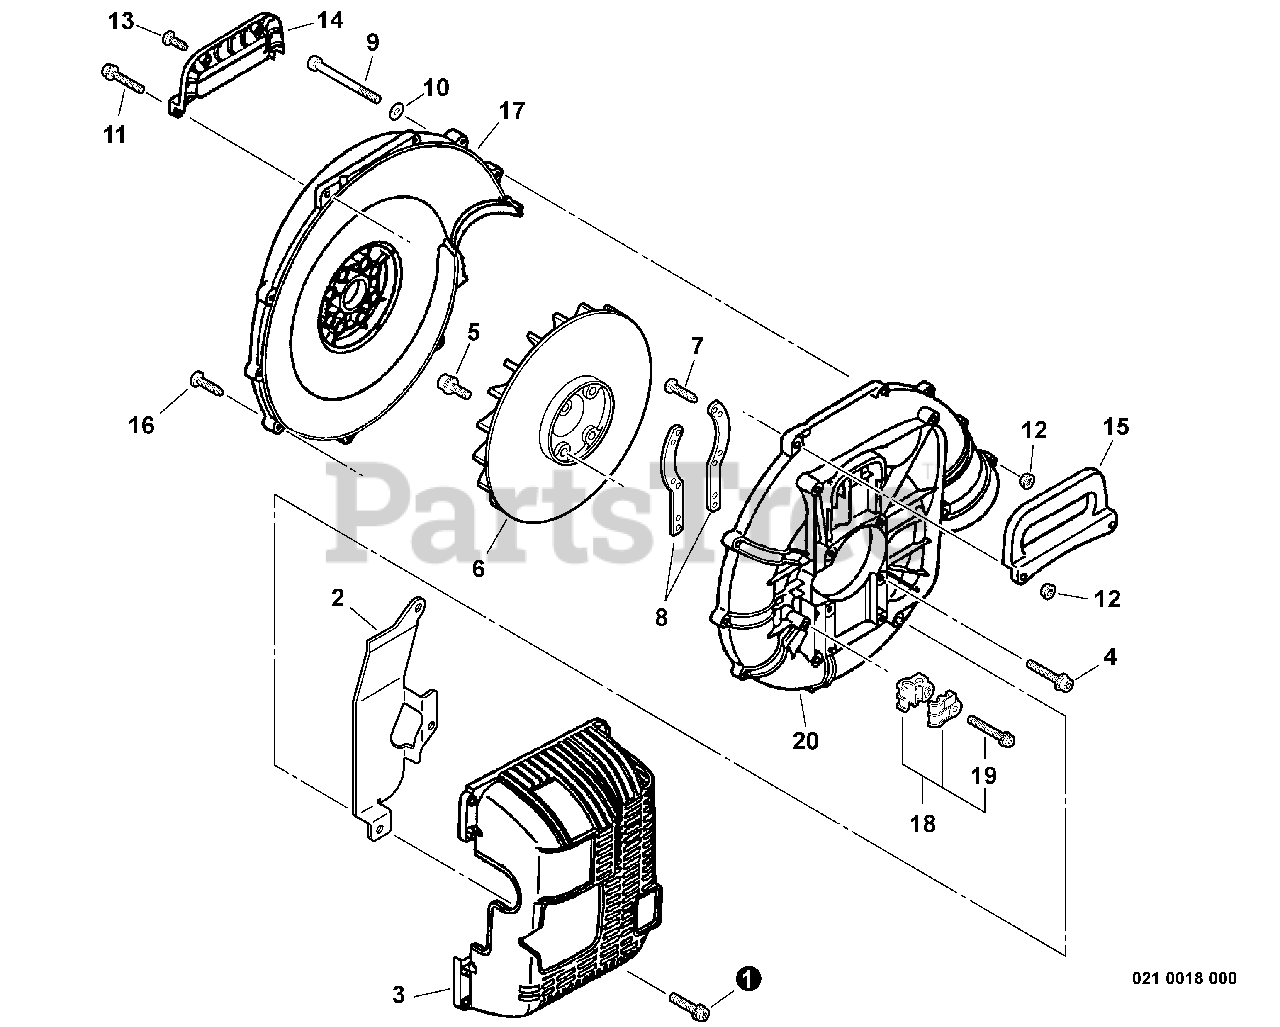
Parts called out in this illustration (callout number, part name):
1	SCREW - 5X18
2	INSULATOR
3	COVER, ENGINE
4	SCREW - 5X32
5	SCREW - 5X20
7	SCREW - 3X12 -- TAPPING
8	BRACKET, ENGINE
9	SCREW - 5X60
10	WASHER - 5
11	SCREW - 5X45
12	NUT - 5 -- FLANGE
13	SCREW - 5X16 -- TAPPING
14	HANDLE - INNER -- GRAY
15	HANDLE - OUTER -- GRAY
16	SCREW - 5X30
17	COVER, FAN - INNER -- GRAY
18	CABLE HOLDER KIT
19	SCREW - 5X25
20	COVER, FAN - OUTER -- GRAY
